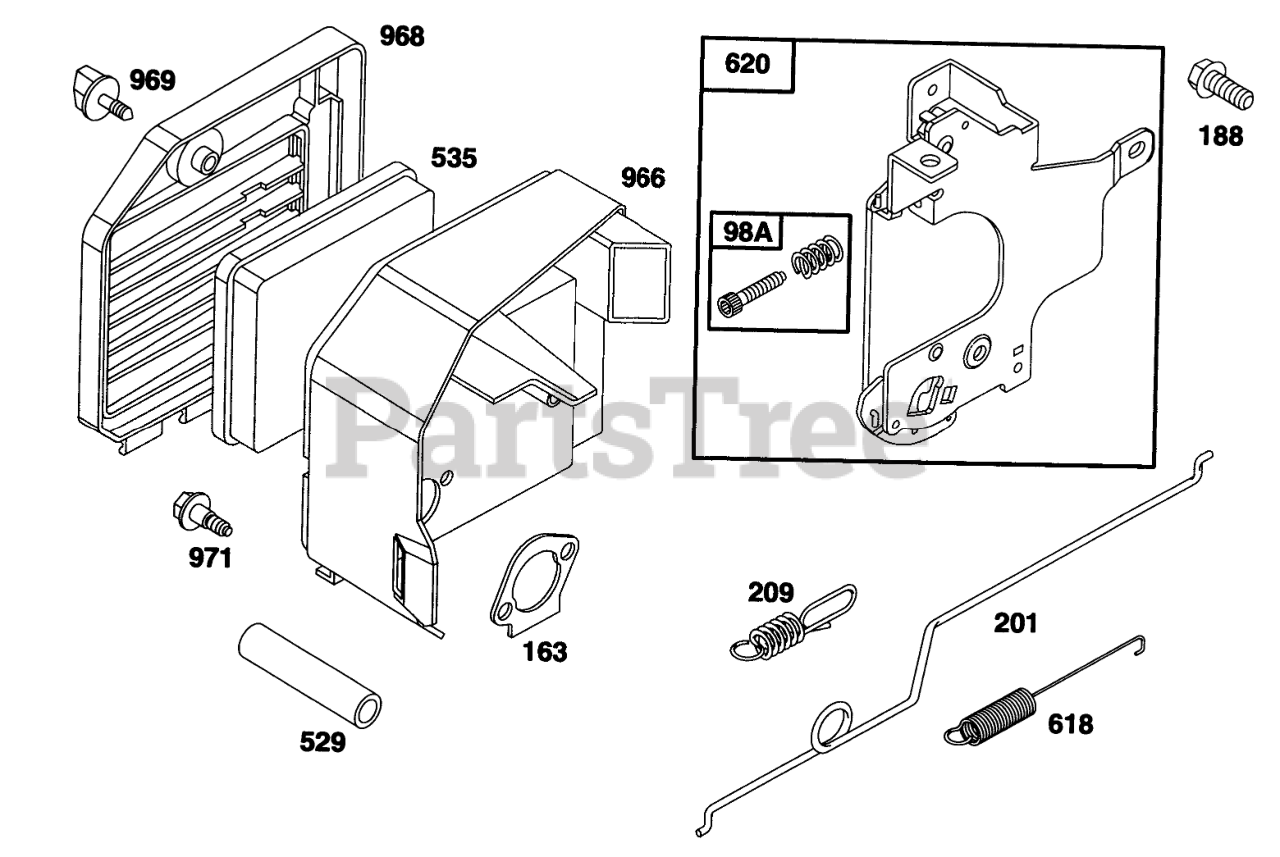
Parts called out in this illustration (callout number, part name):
98A	SPEED ADJUST. SCREW ASM
163	AIR CLEANER GASKET
188	Screw-Cap
201	GOVERNOR LINK
209	GOVERNOR SPRING
529	BREATHER TUBE
535	FILTER ELEMENT
618	RETURN SPRING
620	CARBURETOR BRACKET
966	AIR CLEANER BASE
968	AIR CLEANER COVER
969	AIR CLEANER SCREW
971	AIR CLEANER SCREW
